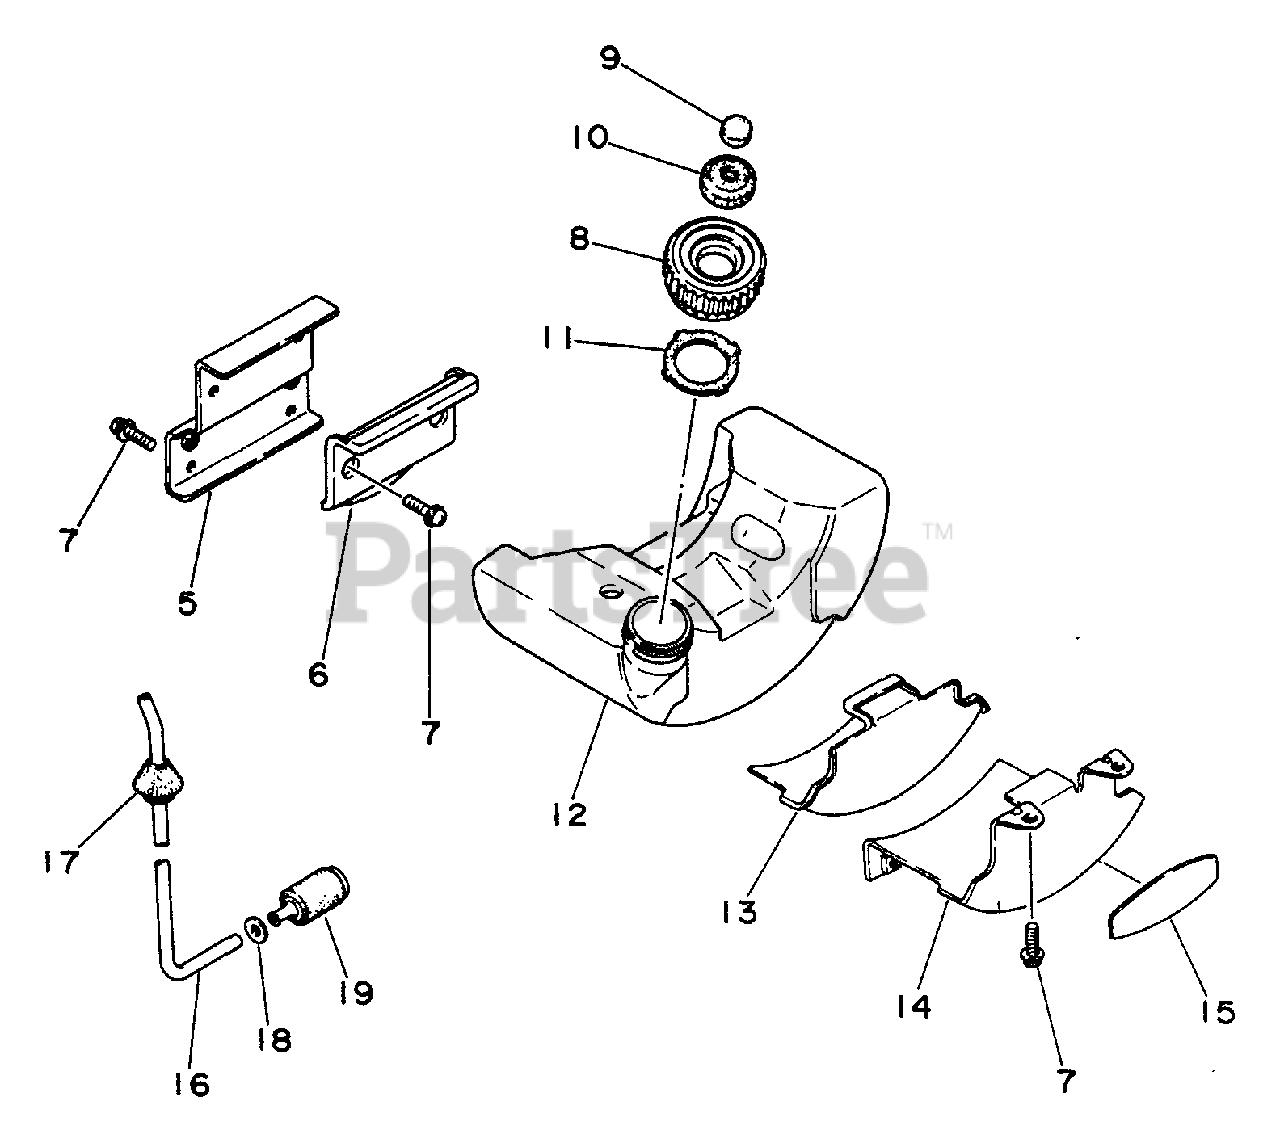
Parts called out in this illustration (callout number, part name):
5	BRACKET, FUEL TANK
6	CUSHION, FUEL TANK
7	SCREW 4×14
8	CAP ASSY
9	FILTER, CHECK VALVE
10	VENT ASSY
12	TANK, FUEL
14	BRACKET, FUEL TANK
15	LABEL - ECHO
18	WASHER 5.5×12×0.8
19	FILTER, FUEL
